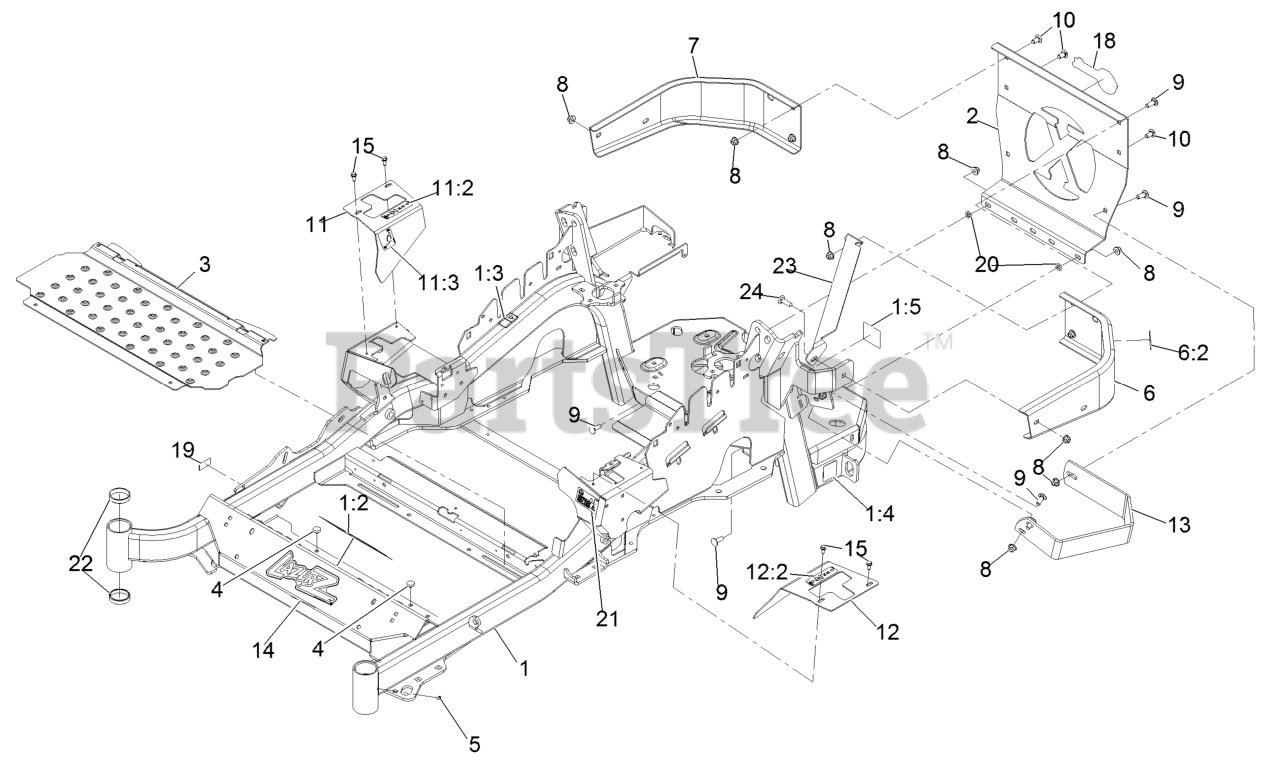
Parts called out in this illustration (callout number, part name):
1	MAINFRAME ASM
1:2	DECAL-WARNING, SLOPE
1:3	DECAL-WARNING
1:4	DECAL-HAZARD, PINCHED FINGER
1:5	DECAL-SPARK ARRESTER
2	PLATE,REAR GUARD
6	LH BUMPER ASM
6:2	DECAL-WARNING
7	BUMPER-RH
8	NUT-HF, NI
9	SCREW-CARR
10	SCREW-CARR
11	RH MOTION CONTROL COVER ASM
11:2	DECAL-CONTROL, MOTION
11:3	DECAL-PARK BRAKE, CE
12	LH MOTION CONTROL COVER ASM
12:2	DECAL-CONTROL, MOTION
13	GUARD-MUFFLER
14	DECAL,LAZER MODEL
15	SCREW-HWH
19	Decal-Patent Ttco.Com
20	NUT-PUSH
21	DECAL-FUEL FILL, CE
22	CUP-BEARING
24	BOLT-CARR
